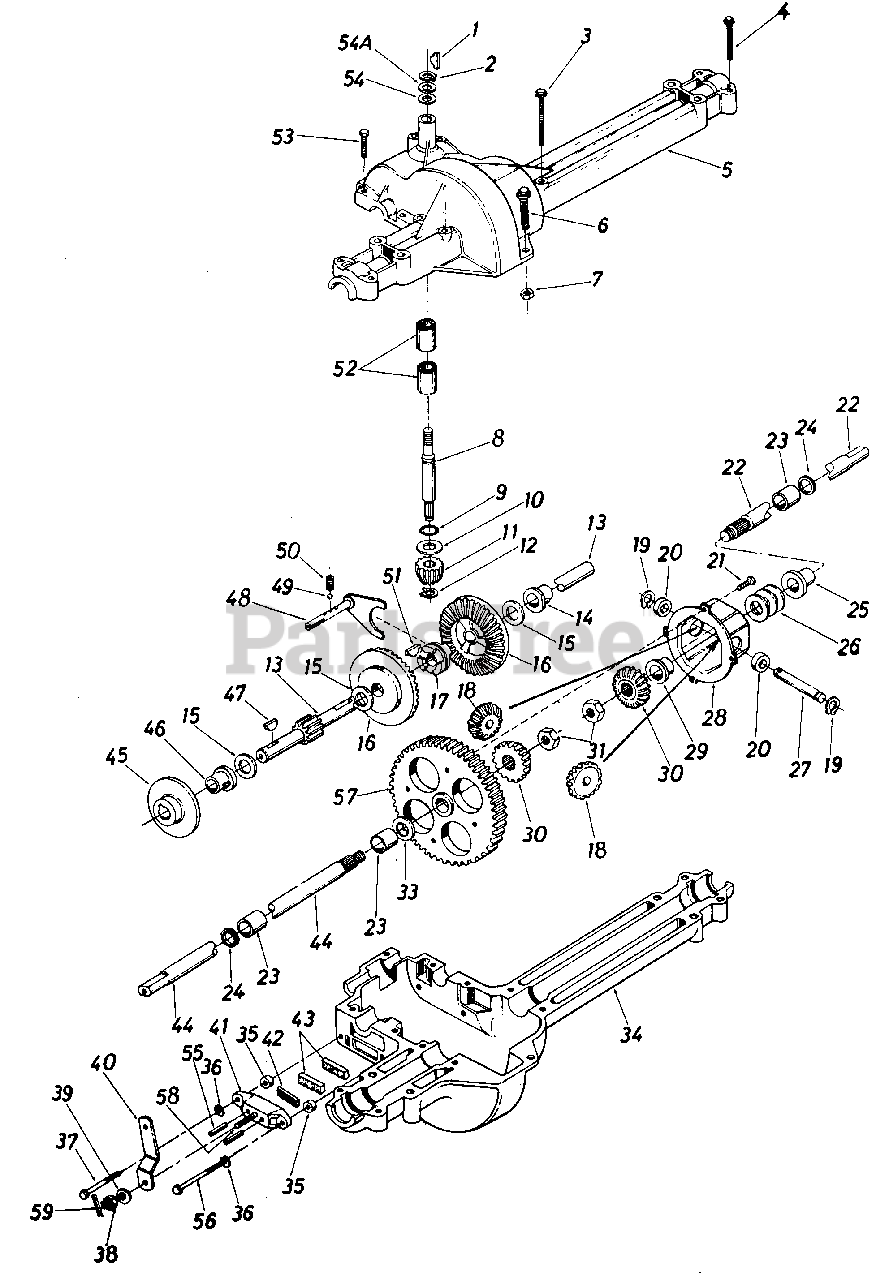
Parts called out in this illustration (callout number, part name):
1	KEY-HI-PRO #4-3/32X5/8 DIA-HDN
2	RING-SNAP FOR .625 DIA SHAFT
3	SCREW-HEX TT-TAP
4	SCREW-HEX 1/4-20 X 1.25
5	HOUSING-UPPER
6	SCREW-HEX FL 1/4-20X.88
7	NUT-HEX 1/4-20
8	SHAFT-INPUT
9	SEAL-SQ
10	WASHER-THRUST-.632X 1.241 X .062
11	PINION-INPUT-14T
12	RING-SNAP FOR .438 DIA SHAFT
13	SHAFT-DRIVE
14	BEARING-FLANGE
16	GEAR-BEVEL
17	COLLAR-CLUTCH
18	GEAR-MITER
19	KIT-DIFF CROSS SHAFT
20	KIT-DIFF CROSS SHAFT
21	SCREW-PAN HD 1/4-20 X .50LG
22	AXLE-RH
23	BEARING-SLEEVE
25	BEARING-FLANGE
26	WASHER-FL-.760ID X 1.49OD X .06HDN
27	KIT-DIFF CROSS SHAFT
28	KIT-DIFF CAN REPL
30	GEAR-MITER
31	RING-SNAP
33	WASHER-FL-.760ID X 1.49OD X .06HDN
34	HOUSING-LOWER
36	LOCK WASHER 1/4 DIA
37	SCREW-HEX 1/4-20X1.50
38	NUT-CASTLE 5/16-24
39	WASHER-FL-.344 ID X .88 OD X .063
40	ARM-ACTUATING
42	PLATE-PUCK
43	PUCK-BRAKE
44	AXLE-LH
45	BRAKE DISC
46	BEARING-FLANGE
47	KEY-HI-PRO
48	FORK ASSY-SHIFT
49	BALL-DETENT
50	SPRING-DETENT FOOTE #333-19
51	KEY-HI PRO
52	BEARING-NEEDLE
53	SCREW-HEX 1/4-20 X 1.00
54	WASHER-FL
54A	WASHER-FL
55	PIN-ACTUATING
56	SCREW-HEX 1/4-20X1.50
57	GEAR-DIFFERENTIAL
58	BOLT-SQ HD SPECIAL
59	PIN-COTTER-3/32 DIA X .75
